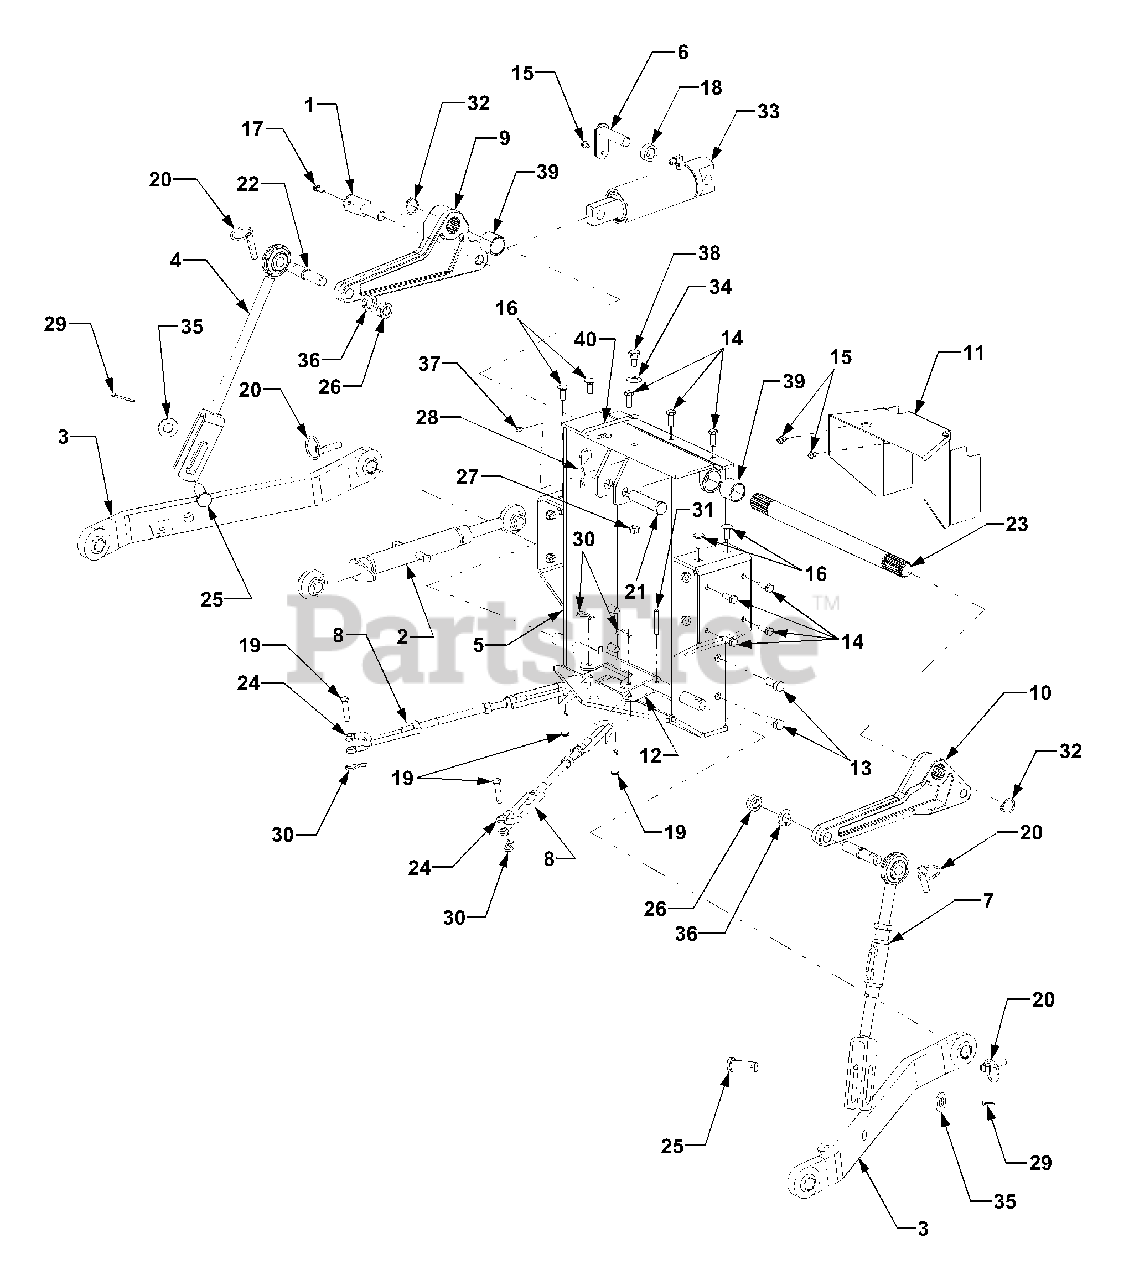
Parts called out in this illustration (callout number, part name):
1	Plate, Cylinder Mounting
2	Link Assembly, Upper
3	Link, Lower
4	Link, Fixed Lift
5	Bracket Assembly, Rear Hitch
6	Plate, Cylinder Mounting
7	Link, Adjustable Lift
8	Chain Assembly, Check
9	Arm, Hitch Lift - LH
10	Arm, Hitch Lift - RH
11	Shield, PTO Shaft
12	Bracket, Chain Mounting
13	Screw, Hex Cap Lock, 1/2-13 x 1.25 GR5
14	Screw, Hex Cap, 3/8-16 x 1.0 GR5
15	Screw, Hex Wash. Hd. Tapp 1/4-20 x .5
16	Screw, Carriage, 3/8-16 x 1.0
17	Screw, Hex Cap, 1/4-20 x .75 GR5
18	Spacer, .75 x 1.25 x .5
19	Pin, Clevis, .372 x 1.79
20	Pin, Klik
21	Pin, Clevis, 19mm x 84mm
22	Pin, Hitch, .75 OD
23	Shaft, Hitch Rock
24	Clevis, Chain
25	Pin, Clevis, .75 x 1.938
26	Nut, Hex Jam, 3/4-10 GR5
27	Nut, Hex Flange Lock, 3/8-16 GRF
28	Pin, Internal Cotter
29	Pin, Cotter, 3/16 x 1.5
30	Pin, Internal Cotter
31	Pin, Spirol, 1/4 x 2.0
32	Ring, Retaining
33	Cylinder, Lift
34	Washer, Belleville, .51 x 1.14 x .04
35	Washer, Flat, .76 x 1.5 x .12
36	Washer, Lock, 3/4
37	Fitting, Lube, 3/16 Drive
38	Screw, Shoulder, 3/8-16
39	Bearing, Sleeve, 1.25 x 1.50 x 1.25
40	Rod, Top Link Hanger
